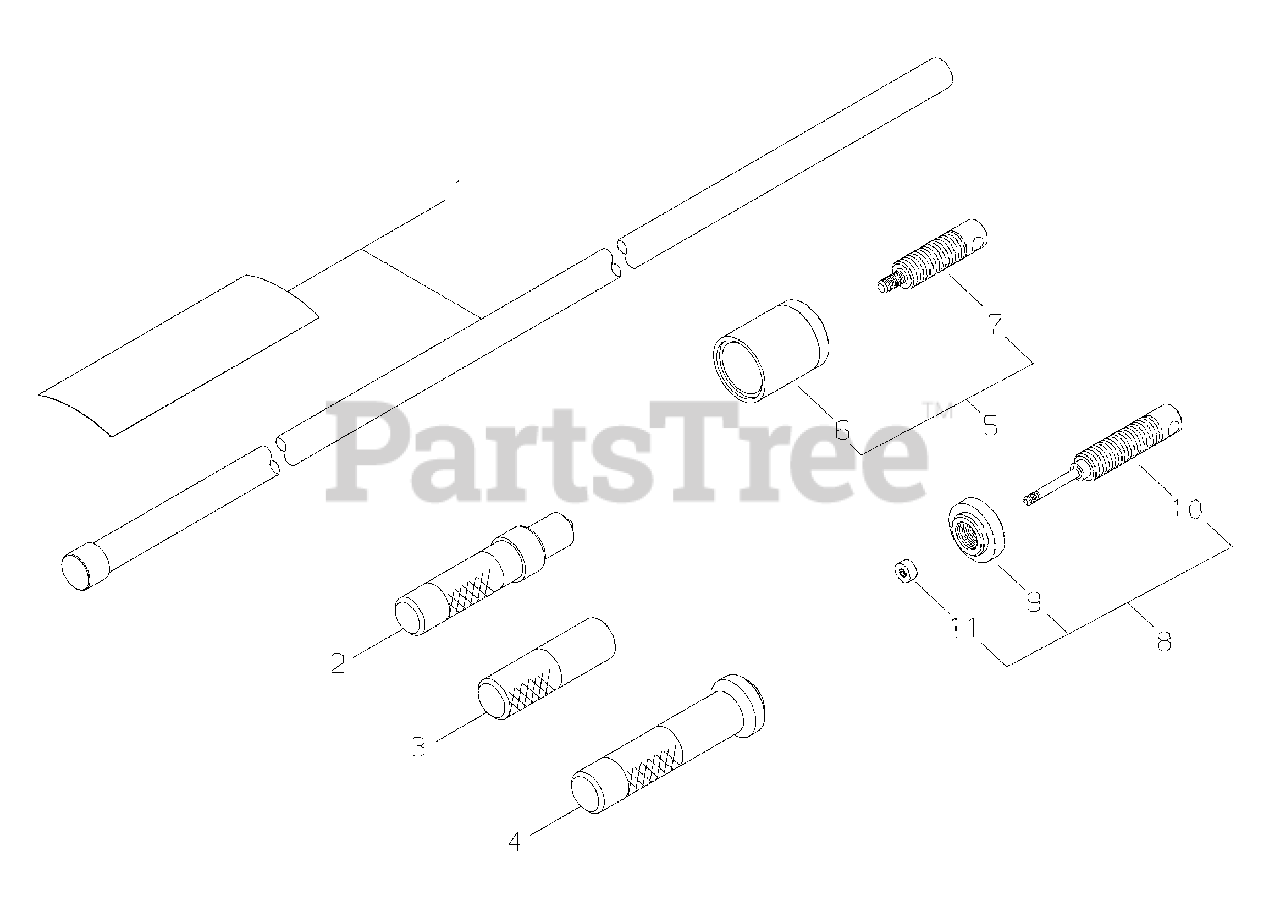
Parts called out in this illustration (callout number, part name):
1	ROD BUSHING ASSY
2	ROD
3	ROD
5	PULLER SUB ASSY
8	PULLER SUB ASSY
9	HOLDER
